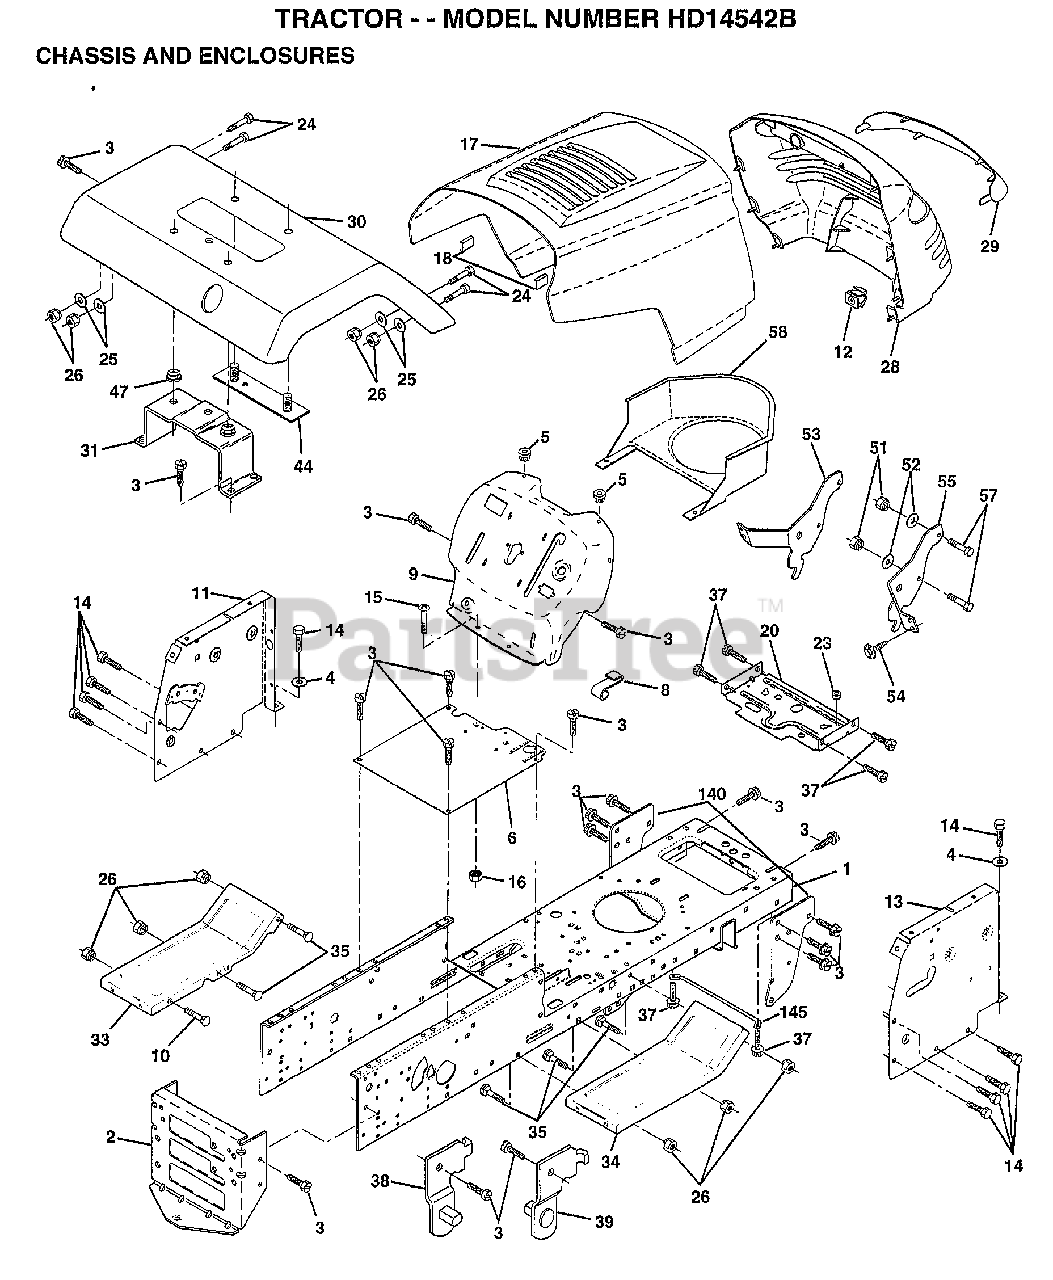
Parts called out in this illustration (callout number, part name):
1	CHASSIS.STAMPING
3	SCREW
4	WASHER
5	BUMPER-HOOD/DASH
6	SADDLE
8	CLIP.RETAINER
9	DASH SILKSCREEN
11	"PANEL-DASH,LH"
12	CLIP.TINNERMAN
14	SCREW LT
15	SCREW
17	"HOOD W/TRIM,MS428"
20	"PLATE-MTG,BATT/FU"
24	BOLT
25	WASHER
26	NUT
28	GRILLE-MS428
29	LENS.GRILLE.PRIVATE LABEL
30	FENDER ASM
31	BRKT FENDER
33	FOOTREST LH
34	FOOTREST RH
35	BOLT
37	SCREW LT
38	BRACKET ASM LH
39	BRACKET ASM RH
51	NUT
52	WASHER
53	BRACKET.GRILLE.LH
54	SCREW.HEX.WS.HD
55	BRACKET.GRILLE.RH
58	AIR DUCT
140	BRKT SUSPENSION
145	"ROD POVOT,CHASSIS"
